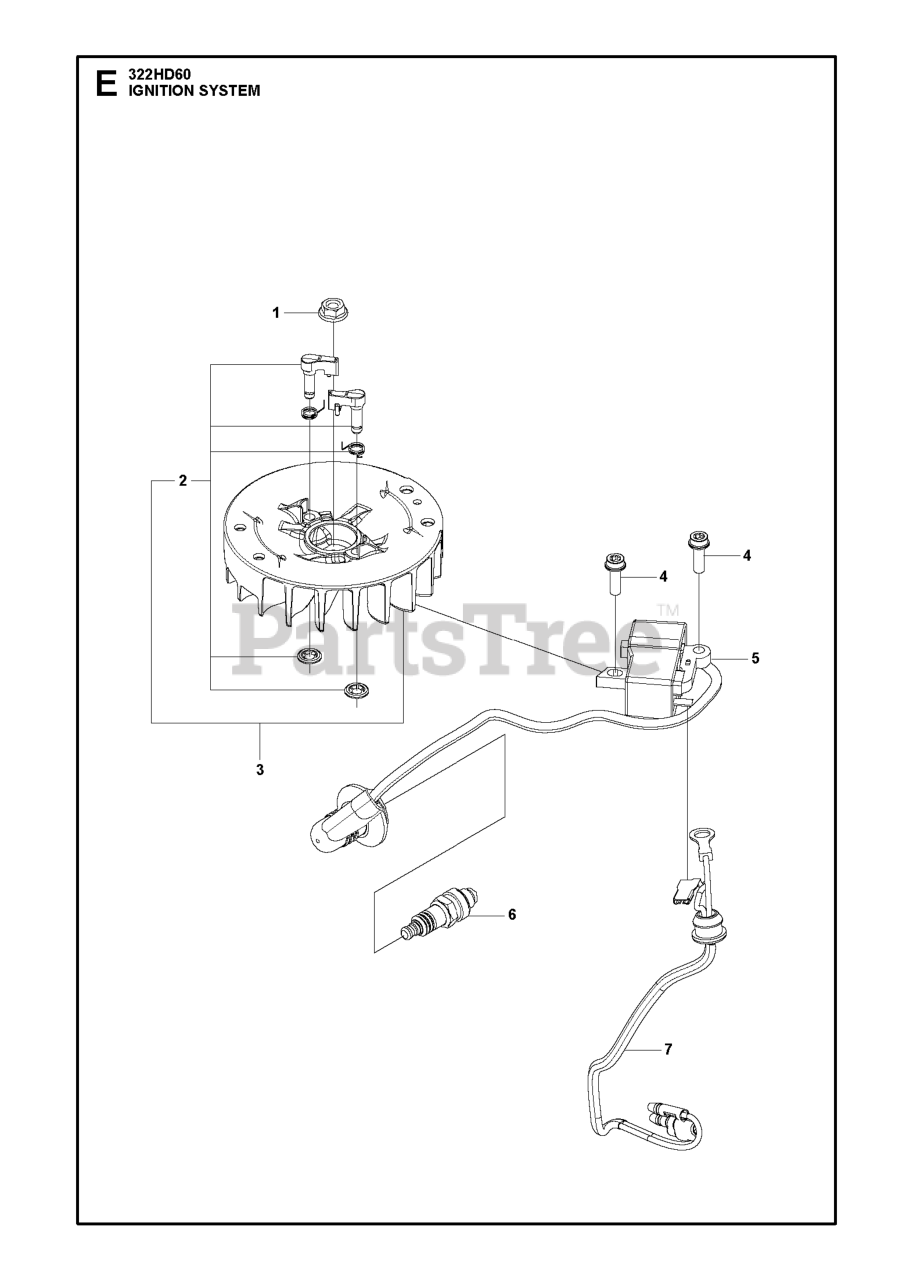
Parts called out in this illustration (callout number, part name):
1	FLANGE NUT
5	IGNITION MODULE A051
6	SPARK PLUG HQT-4 RESISTOR
7	Short Circuit
